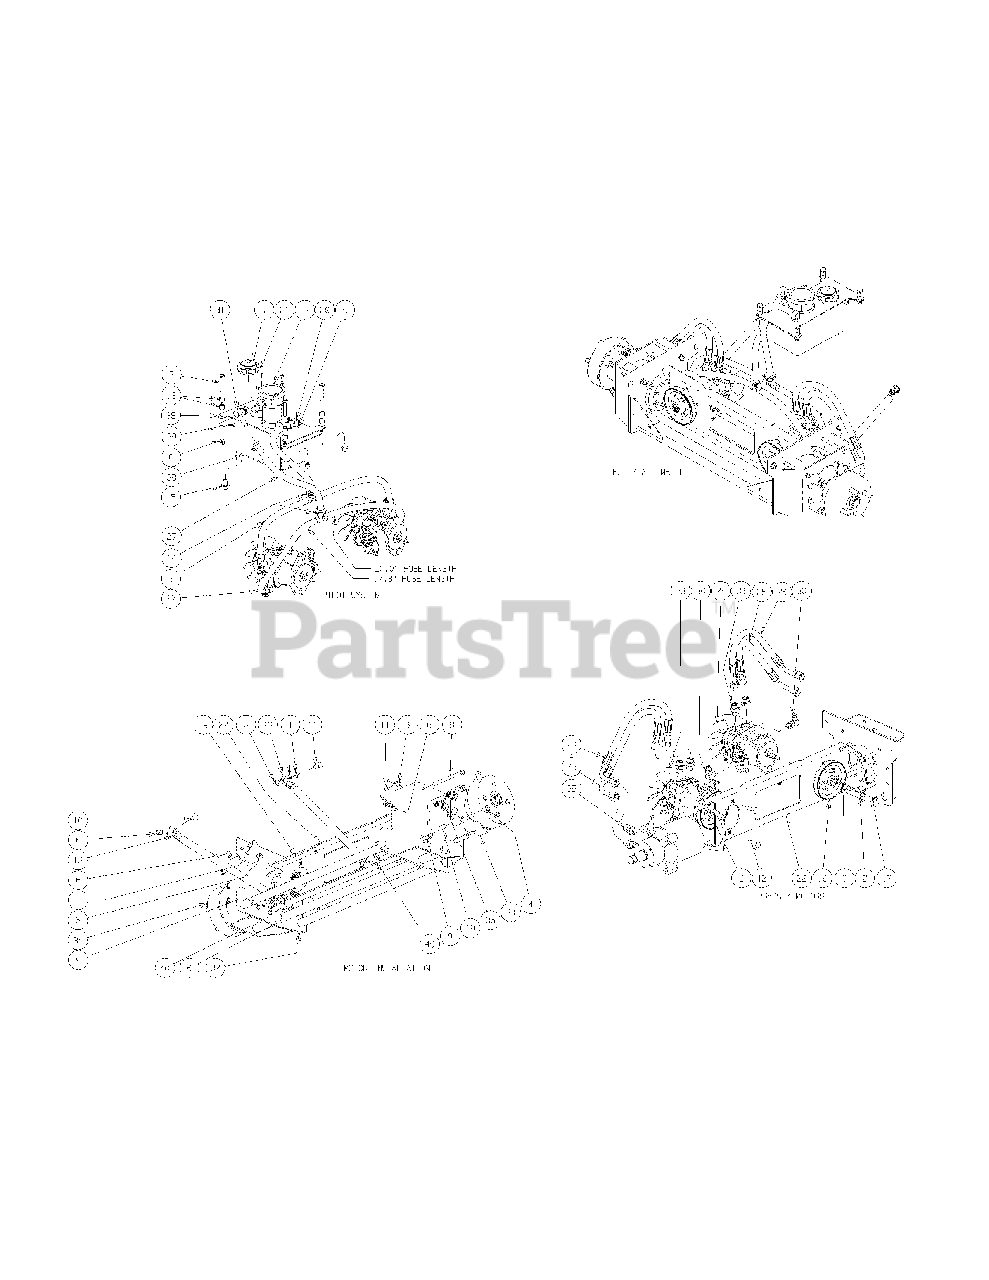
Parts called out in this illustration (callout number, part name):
1	Washer lock 3/8 zinc
2	Flat Washer, 3/8
3	Hex Cap Screw, 3/8-16 x 2.00
4	Washer lock 3/8 zinc
5	Key, 3/16" x 7/8"
6	Flange Lock Hex Nut, 3/8-16
7	Cap, Hydro Oil Tank
8	Hex Cap Screw, 3/8-16 x 5.00
9	Hex Cap Screw, 3/8 -16 x 1.25
10	Carriage Bolt, 3/8-16 x .75 LG.
11	Carriage Bolt, 3/8-16 x 1
12	Carriage Screw, 3/8-16 x 1.25
14	Grommet, .75 ID
15	Oil Pan Drain Plug w/ Seal
16	Hydro Pump Pulley
17	Hex Nut, 3/8-24
18	Spacer, .625 OD x .385 ID x 1/2
19	Socket Head Capscrew, 1/2-13; 6-1/2
20	Grommet Fitting, .54 ID x .78 OD
21	Socket Low Head Cap Screw, 1/4-20 x 0.75
22	Hydro Pump Mounting Bracket
23	Hydro Pump, BDP-12, LH
24	Hydro Pump, BDP-12, RH
25	Hose Assembly
26	Hose Assembly
27	Hose Assembly, Pilot includes:
28	Hose Assembly, Drain includes:
29	Fitting Elbow Spur, 5/8 x 1/2
30	Fitting Elbow, 9/16 x 1/2
31	Fitting Elbow, 3/4 x 1/2
32	Hydro Motor Frame Assembly
33	Hydro Motor, Left Hand Assembly w/ Brake & Drum
34	Hydro Motor, Right Hand Assembly w/ Brake & Drum
35	Adaptor Fitting, 8 x 10
36	Adaptor Fitting, 8 x 8
37	Hydraulic In-Tank Filter includes:
38	Hydraulic Tank Assembly
39	Tank Support Bracket
40	Spacer .406 ID x 1.0 OD
